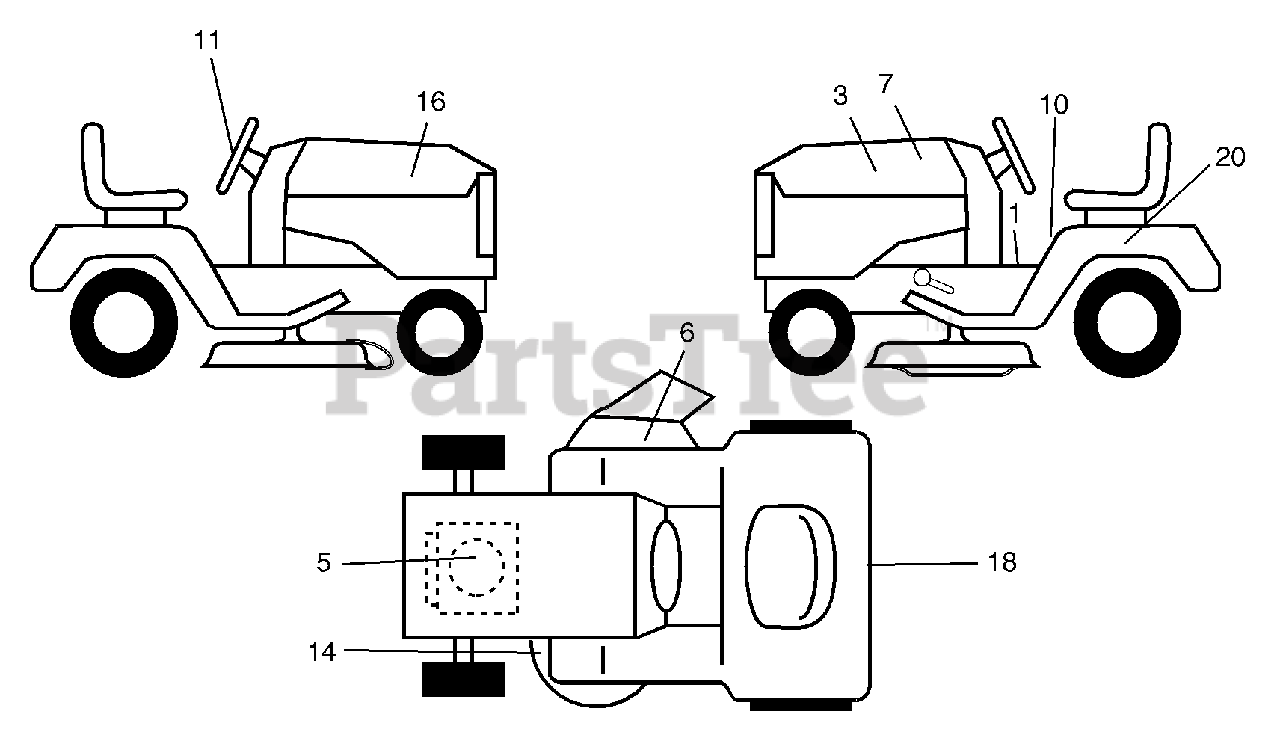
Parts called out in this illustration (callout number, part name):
1	Decal Oper
3	Decal Hood LH
5	Decal HP Engine
7	Decal Repl. Parts
8	Decal Deck "B" 42"
9	Decal Fender Logo
10	Decal Fender Danger E/F
11	Decal Ins Strg Whl
14	Decal V-Belt Schematic
16	Decal Hood Rh
20	Decal Bat Dan/Psn
